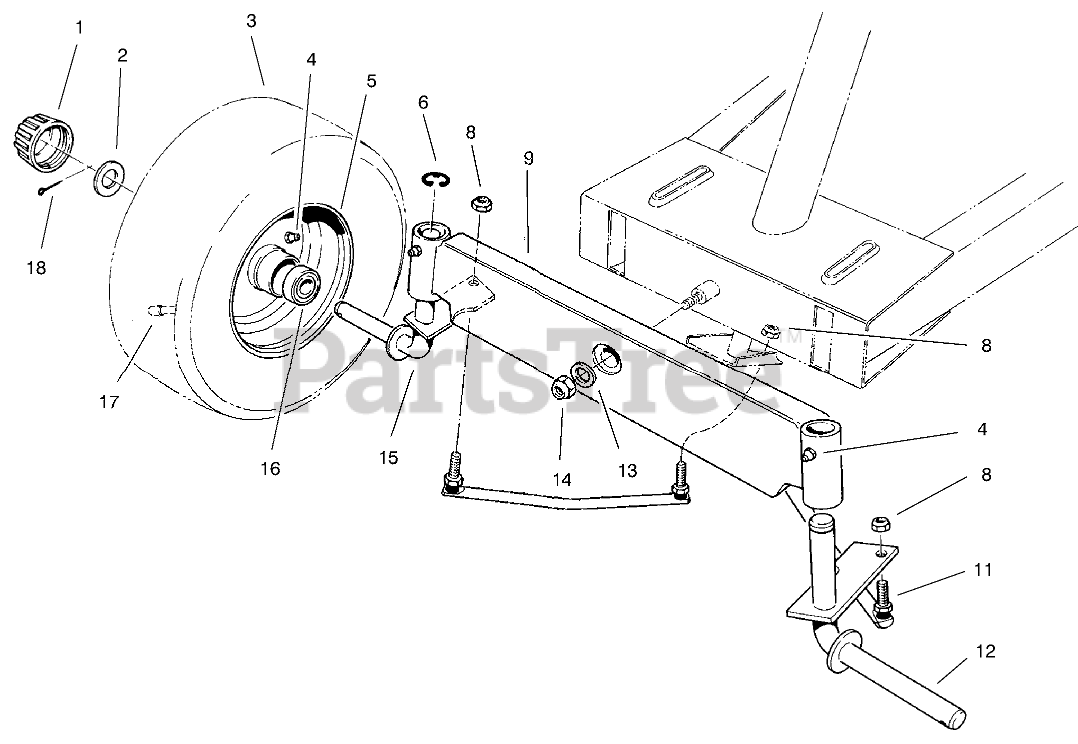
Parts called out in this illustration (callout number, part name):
1	CAP-HUB
2	WASHER-PLAIN
3	TIRE,PNEU.11X4.00X5
4	FITTING-GREASE
6	E-RING
8	NUT-LOCK
9	Axle-Front
11	TIE ROD ASM
12	WHEEL SPDLE WA LH (RED)
13	WASHER-FLAT
14	NUT-LOCK, NI
15	WHEEL SPDLE WA RH (RED)
16	BEARING-WHEEL
17	STEM-VALVE
18	PIN-COTTER
